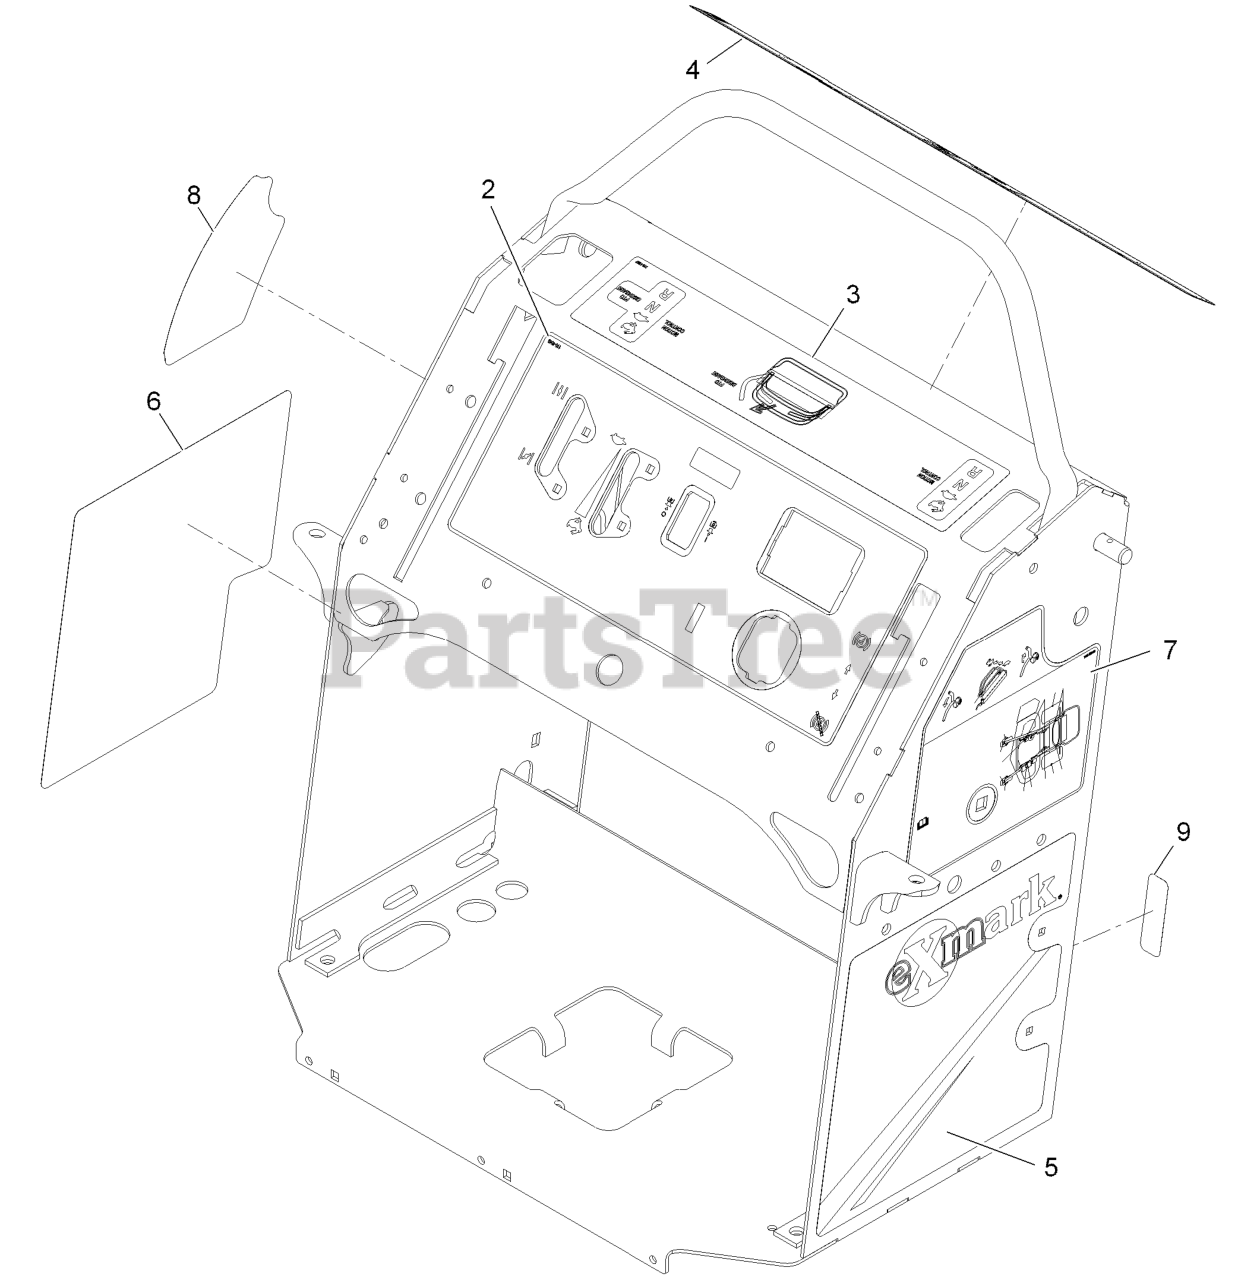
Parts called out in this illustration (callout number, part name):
2	DECAL-CONTROL PANEL
3	DECAL-MOTION CONTROL
4	DECAL-WARNING
5	DECAL-LH PANEL
6	DECAL-RH PANEL
7	DECAL-SERVICE AID
8	DECAL-HEIGHT OF CUT
9	DECAL-FUSE
